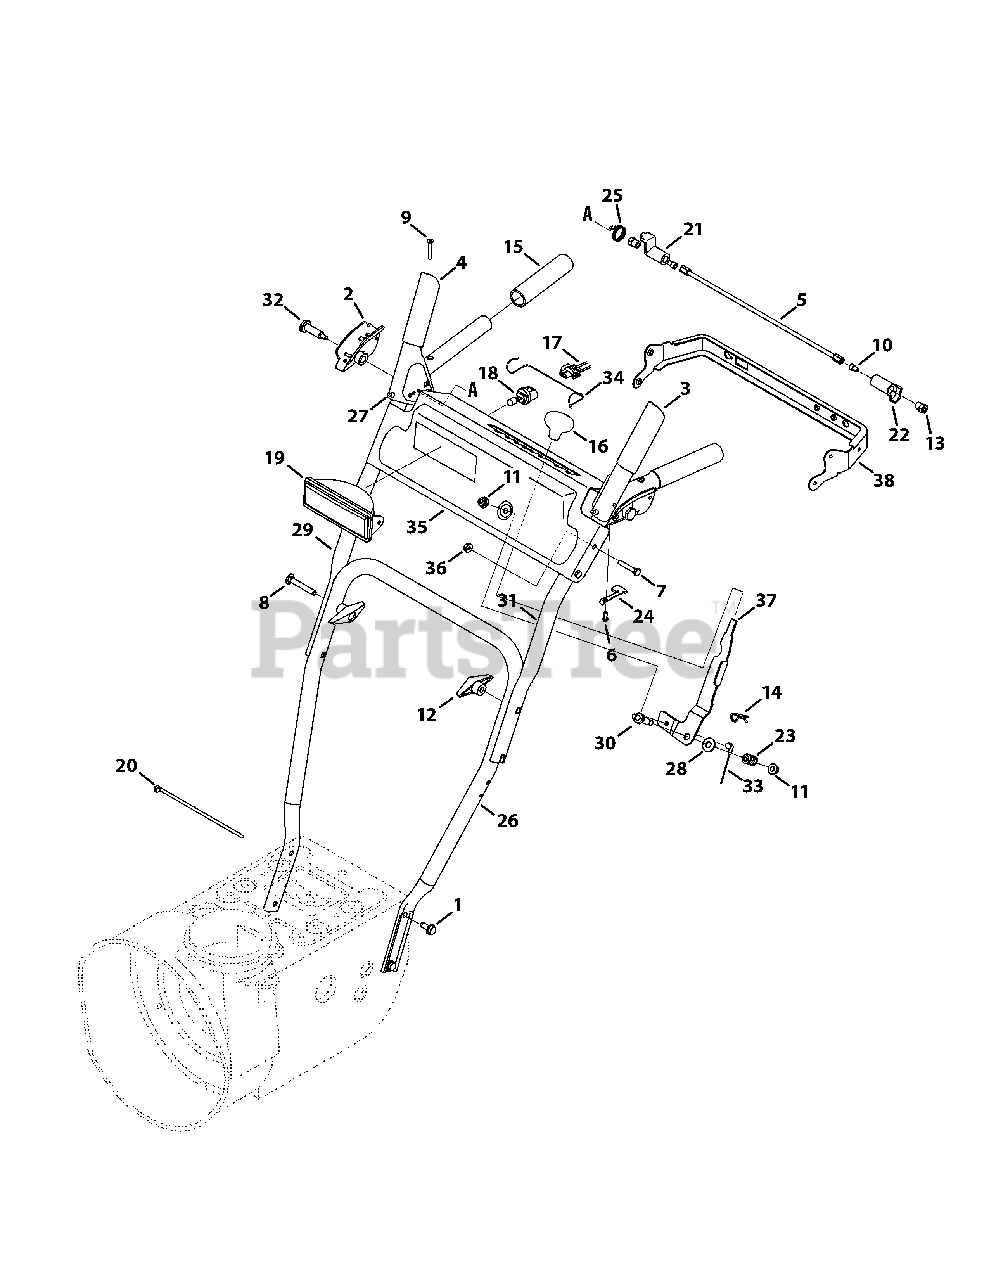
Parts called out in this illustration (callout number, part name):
1	Taptite Screw, 5/16-18 x .750
2	Clutch Lock Handle Assembly, LH
2	Clutch Lock Handle Assembly, RH
3	Engagement Assembly, LH
4	Engagement Assembly, RH
5	Clutch Pivot Lock Rod Assembly
6	Hex Washer Screw, #8-16 x .50
7	Hex Washer Screw, 1/4-20 x .625
7	Hex Head Screw, 1/4-20 x 1.50
8	Carriage Screw, 5/16-18 x 2.25
9	Machine Screw, #10-24 x 1.375
10	Socket Screw, 1/4-20 x .50
11	Flange Lock Nut, 5/16-18
12	Wing Knob
13	Hex Nut, 1/4-20
14	Click Pin, .092 x 1.64
15	Grip, 1.0 ID x 5.0 LG
16	Shift Knob
17	Snow Thrower Harness
18	Halogen Lamp
19	Lens/Lamp Assembly Housing
20	Cable Tie
21	Lock Plate
22	Clutch Lock Cam
23	Compression Spring, .39 x .60 x .88
24	Clutch Lock Spring
25	Torsion Spring, .8156 ID x .3038
26	Lower Handle
27	Rubber Bumper, .62 OD x .22 Thick
28	Flat Washer, .385 x .870 x .092
29	Upper RH Handle
30	Shoulder Bolt, 5/16-18 x .905
31	Upper LH Handle
32	Shoulder Screw, .437 x 1.345 x 1/4-20
33	Speed Selector Cable
34	Headlight Retainer
35	Handle Panel w/ Light - Powder Black
35	Handle Panel w/ Light - Red
35	Handle Panel w/ Light - Black Jack
35	Handle Panel w/o Light - Powder Black
35	Handle Panel w/o Light - Red
35	Handle Panel w/o Light - Black Jack
36	Flange Lock Nut, 1/4-20
37	Speed Shift Lever
38	Panel Bracket
